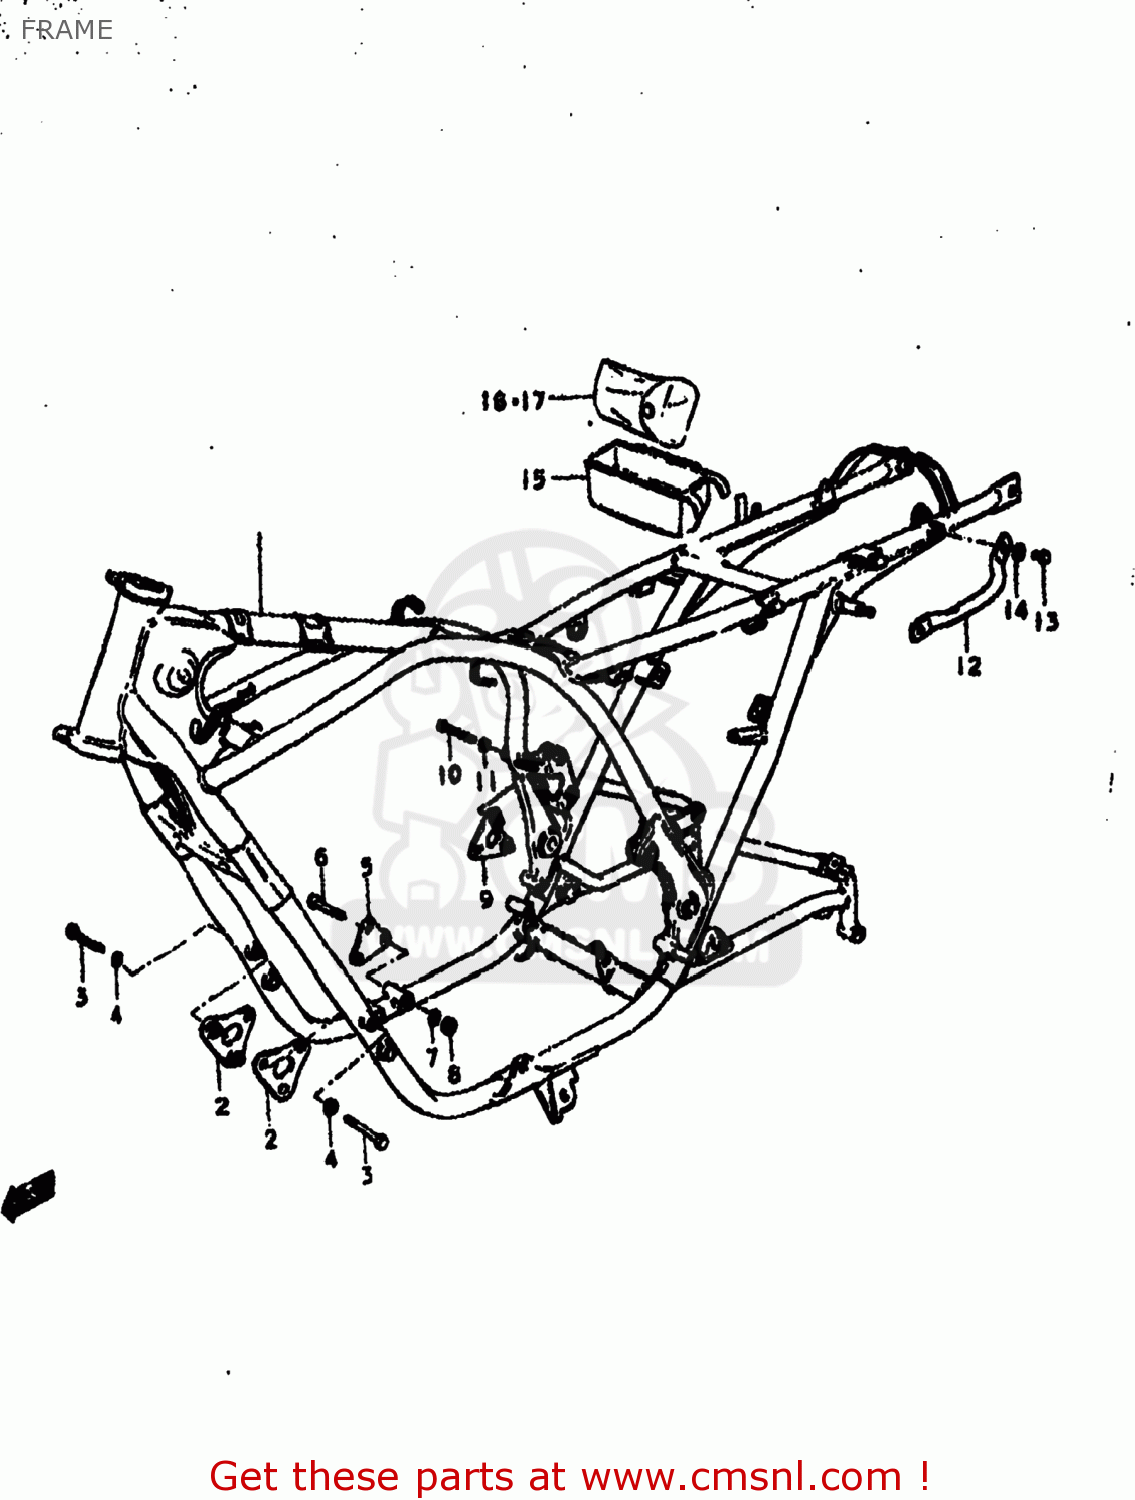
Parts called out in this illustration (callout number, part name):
1	FRAME
2	PLATE,ENGINE MOUNTING
3	BOLT
4	LOCK WASHER
5	PLATE,ENGINE MOUNTING
6	BOLT
7	LOCK WASHER
8	NUT
9	PLATE,ENGINE MOUNTING
10	BOLT 8X55
11	LOCK WASHER
12	GRIP,FRAME HANDLE
13	BOLT
14	WASHER
15	HOLDER,TOOL
16	TOOL SET
17	TOOL SET
